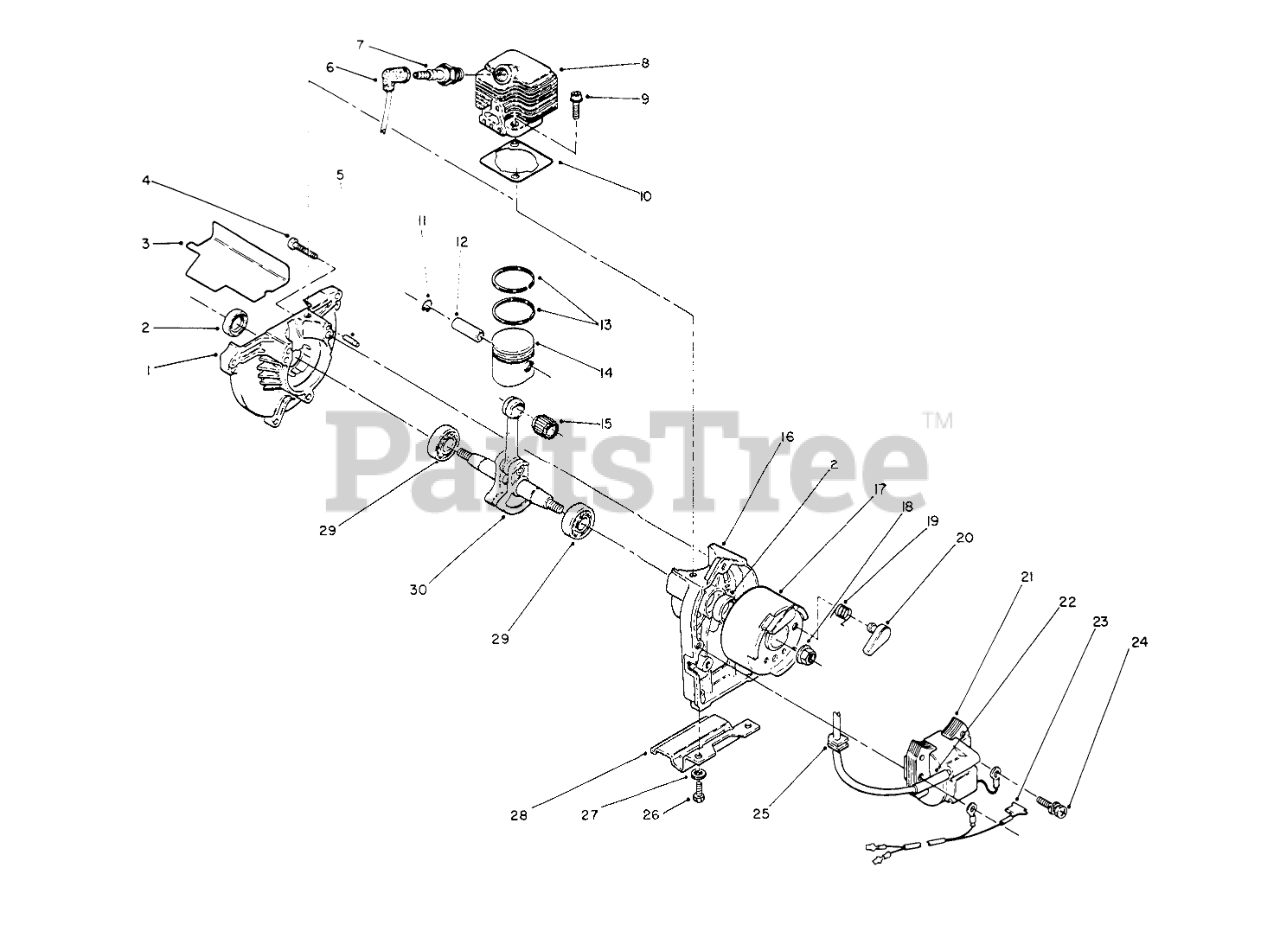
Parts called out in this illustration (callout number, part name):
1	Case-Drive
2	OIL SEAL
3	BAFFLE GASKET
4	Screw
6	PLUG BOOT
7	Plug-Spark
8	CYLINDER
9	FLANGE BOLT
10	CYL GASKET
11	PISTON PIN CLIP
12	PISTON PIN
13	TOP RING
14	Piston Ass-y (Incl. Ref. #12)
15	NEEDLE BEARING
16	STARTER CASE
17	Flywheel (Incl. Ref. #19 & 20)
19	RETURN SPRING
20	RATCHET
21	IGNITION COIL
23	LEAD WIRE
24	BOLT AND WASHER
25	GROMMET
26	M6 X 1 X 1/2 MWH SCREW
27	WASHER-LOCK
28	STAND SUPPORT
29	BEARING
30	CRANKSHAFT ASSEMBLY
